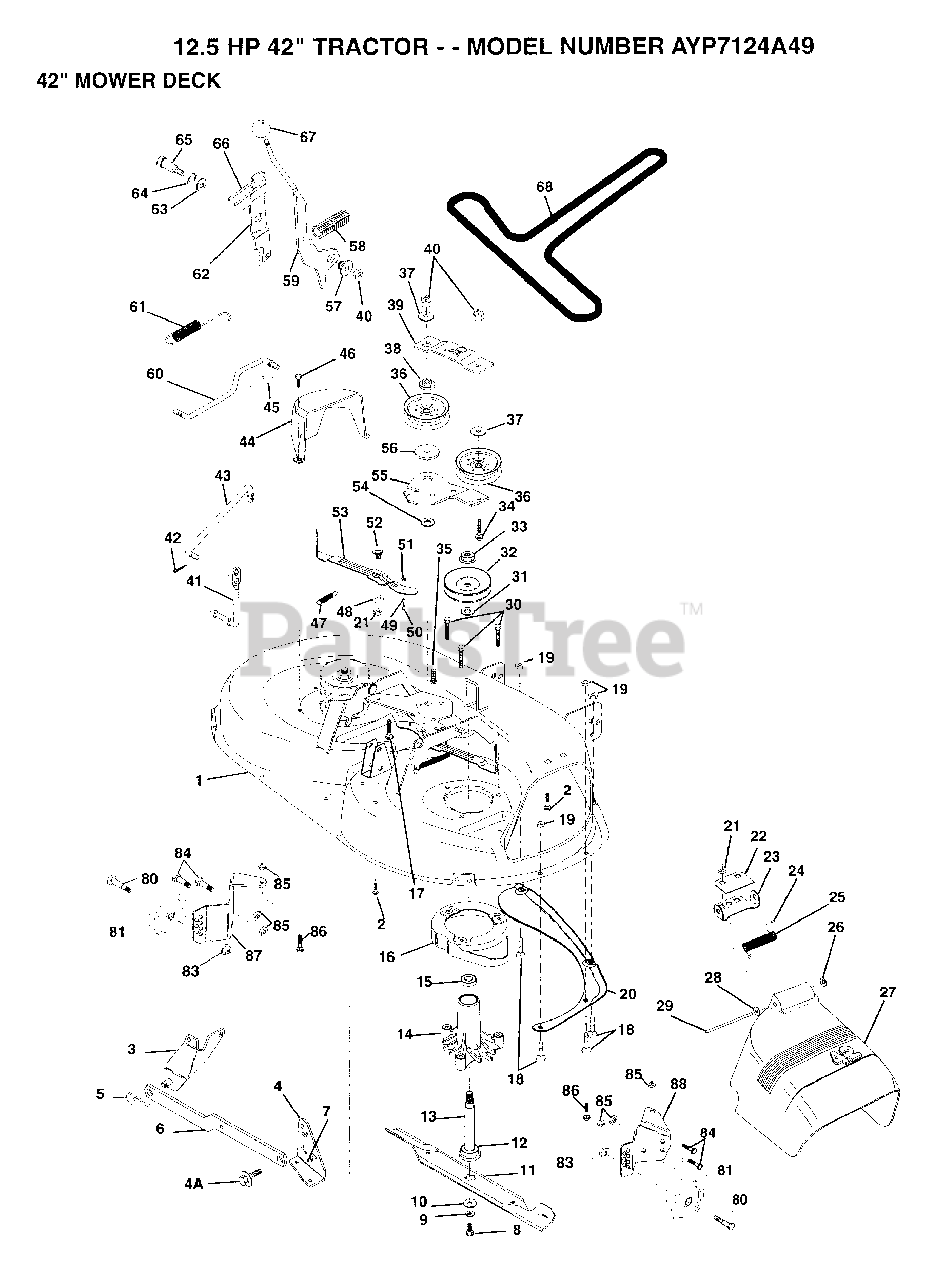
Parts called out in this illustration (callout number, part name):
2	BOLT
3	BRKT ASM SWAY BAR
4	BRKT SWAY BAR
4A	BOLT SHD 5/16-18
7	NUT
8	BLADE BOLT
10	WASHER.HARD.BLADE
11	"BLADE.42"" MULCHER"
12	BEARING.BALL
14	HSG ASM MANDREL
15	BEARING
17	BOLT CARRIAGE
18	BOLT
19	NUT
22	STIFFENER BRKT
23	DEFLECTOR BRKT
24	CAP-SLEEVE LT
25	SPRING TORSION
26	NUT PUSH M
27	DEFLECTOR.SHIELD
28	WASHER
29	HINGE ROD
31	WASHER
34	BOLT
35	XMAS TREE FASTNER
36	FLAT IDLER PULLEY
37	WASHER GT
38	RETAINER SPACER
39	IDLER ARM STIFF
41	PIVOT ROD
43	CLUTCH ROD SECOND
44	ROD CLUTCH W/NIBS
45	RETAINER M
46	SCREW.1/4-20X5/8
47	SPRING EXTENSION
48	HARD SMALL WASHER
50	SHOULDER BOLT
51	LOCKNUT
52	BOLT.SHLD.5/16-18
53	BRAKE PAD ARM ASM
54	HARDENED WASHER
55	IDLER ARM
56	SPACER RETAINER
57	BUSHING
59	CLUTCH ARM PRI AS
60	"ROD, CLUTCH PRIM"
61	RETURN SPRING
62	CLUTCH ARM SECOND
63	WASHER
64	RING
65	SHOULDER BOLT
66	SPRING KEEPER
67	KNOB T(3/8 HOLE)
68	BELT-V.92.4.MWR
80	BOLT M
81	WHEEL.GAGE.BLK.PL
83	NUT
84	BOLT
